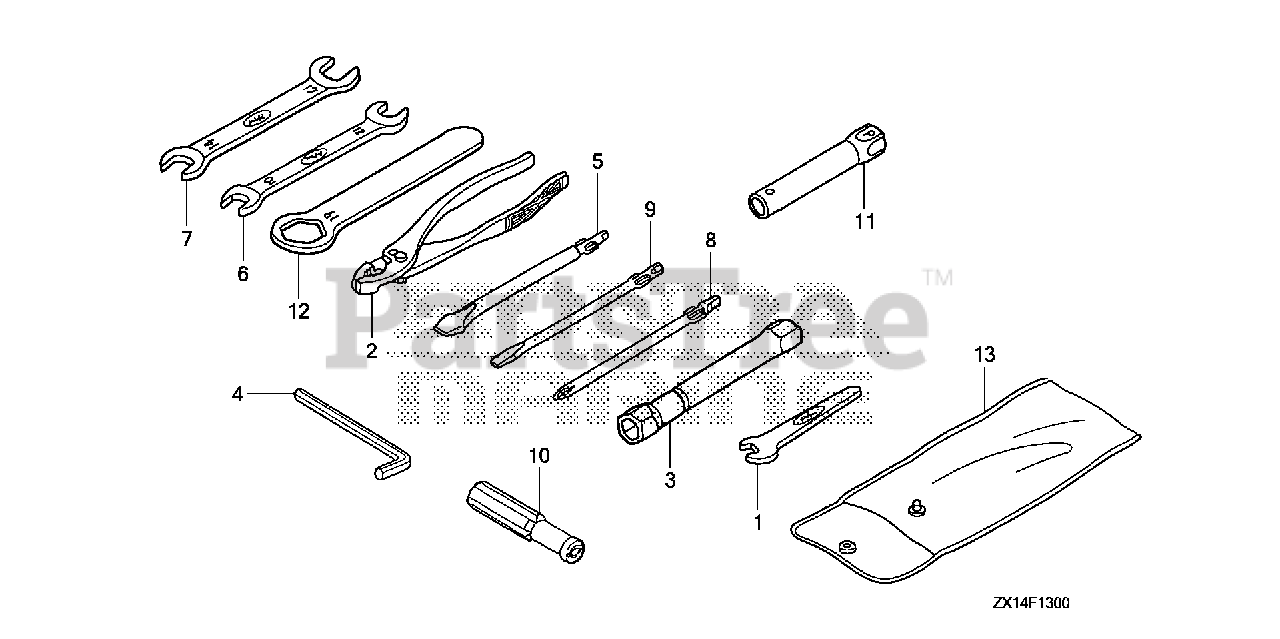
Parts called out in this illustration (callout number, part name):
1	WRENCH (8MM) (OPEN END) (NOT AVAILABLE)
2	PLIERS (135) (RIKEN)
3	WRENCH, PLUG
4	WRENCH, HEX. (6MM)
5	SCREWDRIVER, CHECK BOLT
6	WRENCH (10X12) (OPEN END)
7	WRENCH (14X17) (OPEN END)
8	SCREWDRIVER 1, PHILLIPS (NO.2)
9	SCREWDRIVER 3, STRAIGHT SLOT (NO. 2)
10	GRIP, SCREW DRIVER
11	WRENCH, BOX (P16X17)
12	WRENCH, EYE (19MM)
13	BAG, TOOL (230MM)
